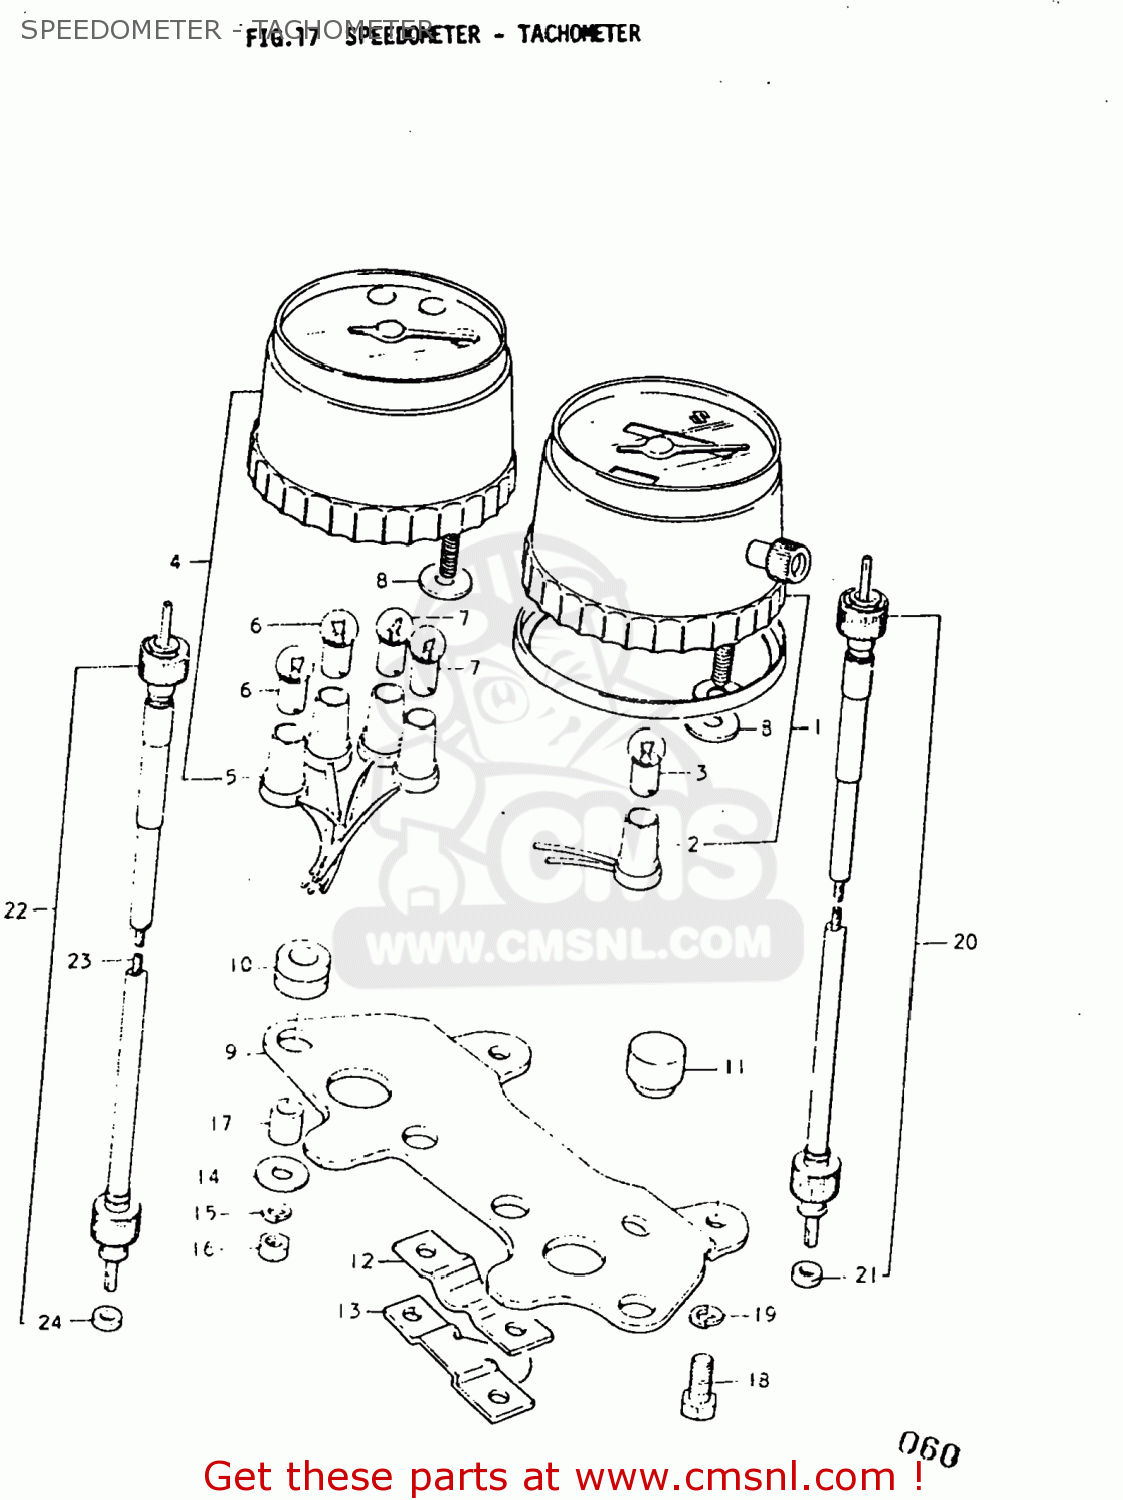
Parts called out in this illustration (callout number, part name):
1	SPEEDOMETER ASSEMBLY
2	SOCKET,METER
3	BULB(6V/3W)
4	METER,TACHOMETER
5	SOCKET,TACHOMETER
6	BULB(6V/3W)
7	BULB(6V1.7W,STANLEY,A61A)
8	WASHER (5.5X16X1.2)
9	BRACKET,METER
10	CUSHION
11	CUSHION,METER
12	COVER,METER,UNDER
13	COVER,METER,UNDER
14	WASHER (5.5X16X1.2)
15	LOCK WASHER
16	NUT
17	SPACER,METER NO.2
18	BOLT
19	LOCK WASHER
20	CABLE ASSY,SPEEDOMETER
21	SEAL,OIL METER CABLE
22	CABLE ASSY,TACHOMETER
24	OIL SEAL,SPEEDOMETER CABLE
